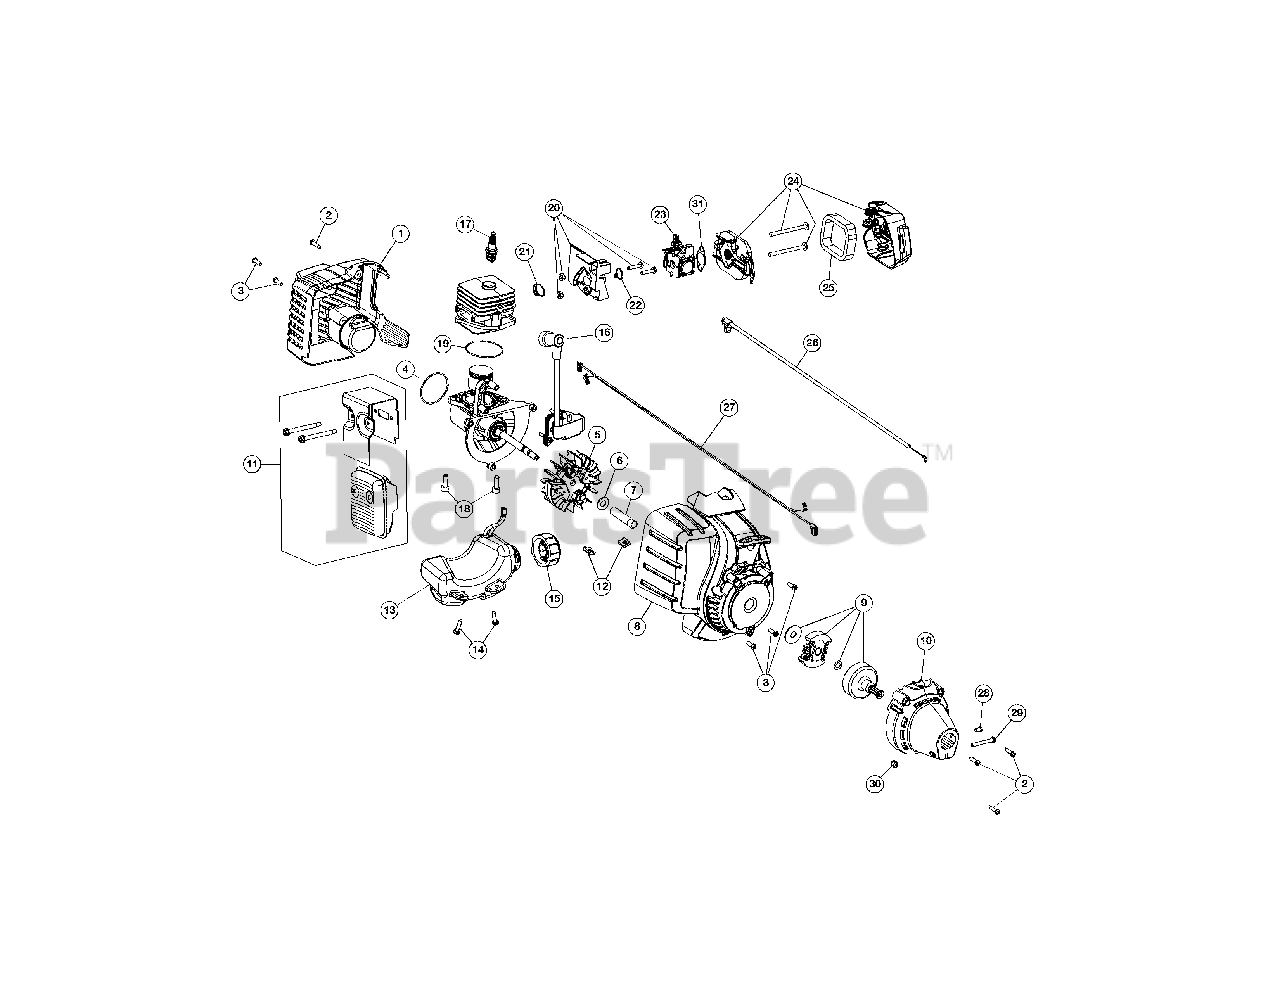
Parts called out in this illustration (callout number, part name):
1	Rear Cover Assembly (Incl. 2 & 3)
2	Cover Screw
3	Housing Screw
5	Flywheel Assembly
8	Starter Housing (Incl. 3 & 12)
9	Clutch Assembly
10	Clutch Cover (Incl. 2)
11	Muffler Assembly
12	U-shaped Nut
13	Fuel Tank Assembly (Incl. 14 & 15)
16	Module Assembly
17	Spark Plug
18	Crankcase Bolt
19	Crankcase O-Ring
20	Insulator Assembly (Incl. 21 & 22)
21	Insulator O-Ring
22	Carburetor O-Ring
23	Carburetor
24	Aircleaner Cover Assembly (Incl. 25)
25	Aircleaner Filter
26	Throttle Cable
27	Lead Wires
28	Anti-rotation Screw
29	Clamp Screw
30	Clamp Nut
31	Air Cleaner Gasket
